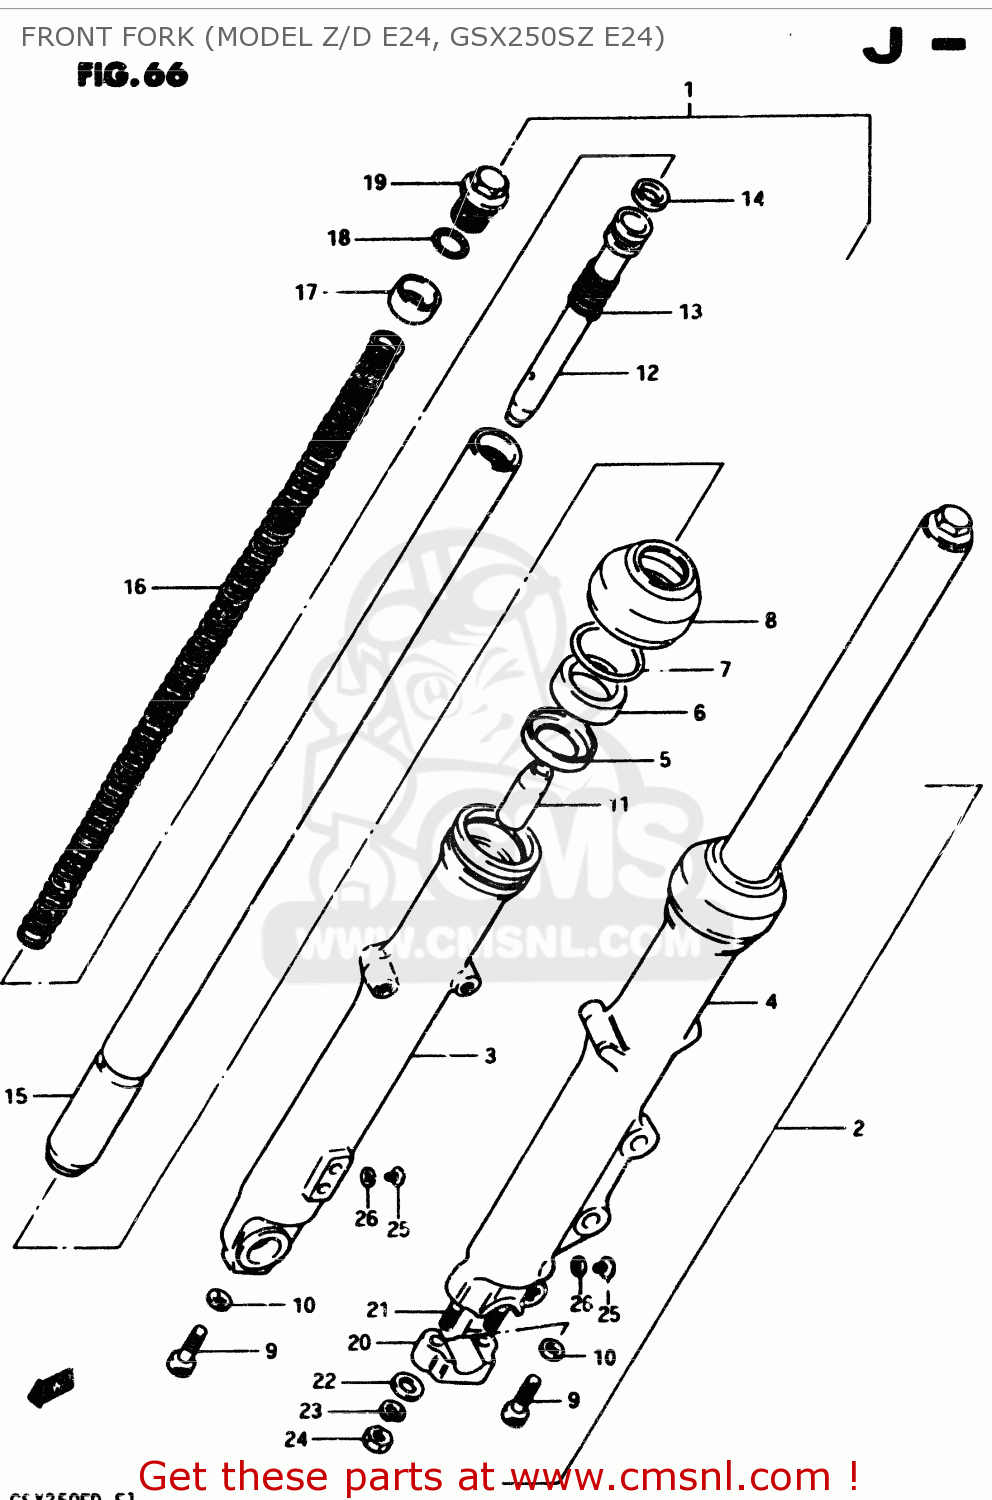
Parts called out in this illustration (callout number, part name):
1	DAMPER ASSY, RH
2	DAMPER ASSY, LH
3	TUBE,FORK,OUTER,RIGHT
4	TUBE,FORK,LEFT,OUTER
5	SPACER,OIL SEAL
6	OIL SEAL,FRONT FORK
7	RING,OIL SEAL STOPPER
8	DUST SEAL
9	BOLT(8X27)
10	GASKET (NAS)
11	PIECE,OIL LOCK
12	CYLINDER,FRONT FORK
13	SPRING,REBOUND
14	RING,PISTON
15	TUBE,INNER
16	SPRING
17	SPACER,FRONT FORK SPRING
18	O RING
19	BOLT
20	HOLDER,AXLE
21	STUD 8X25
22	WASHER
23	LOCK WASHER
24	NUT
25	SCREW 4X6
26	GASKET (NAS)
